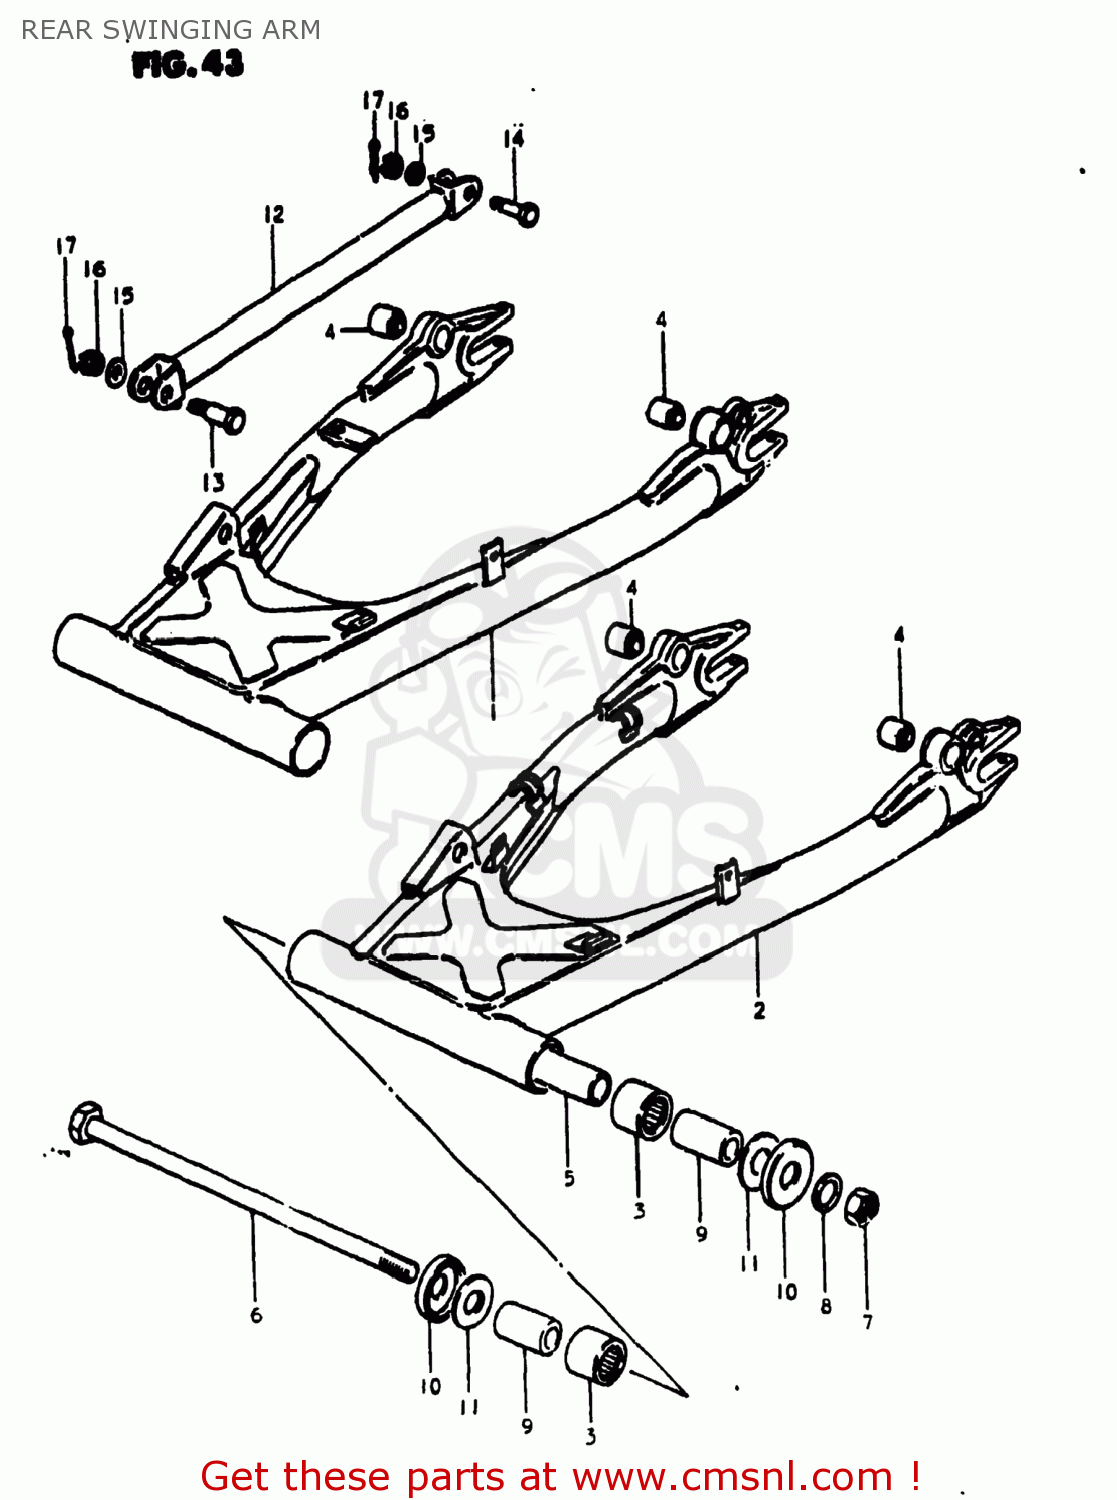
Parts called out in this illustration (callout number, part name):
1	SWING ARM ASSEMBLY,REAR
2	SWING ARM ASSEMBLY,REAR
3	BEARING(25X33X30)
4	BUSH
5	SPACER,RR SWGARM PIVOT CTR
6	SHAFT,REAR SWING ARM
7	NUT 16MM
8	WASHER
9	SPACER,RR SWGARM PIVOT
10	COVER,RR SWGARM DUST SEAL
11	WASHER
12	LINK,REAR TORQUE
13	BOLT
14	BOLT(10X39)
15	WASHER
16	NUT
17	PIN 20X20
